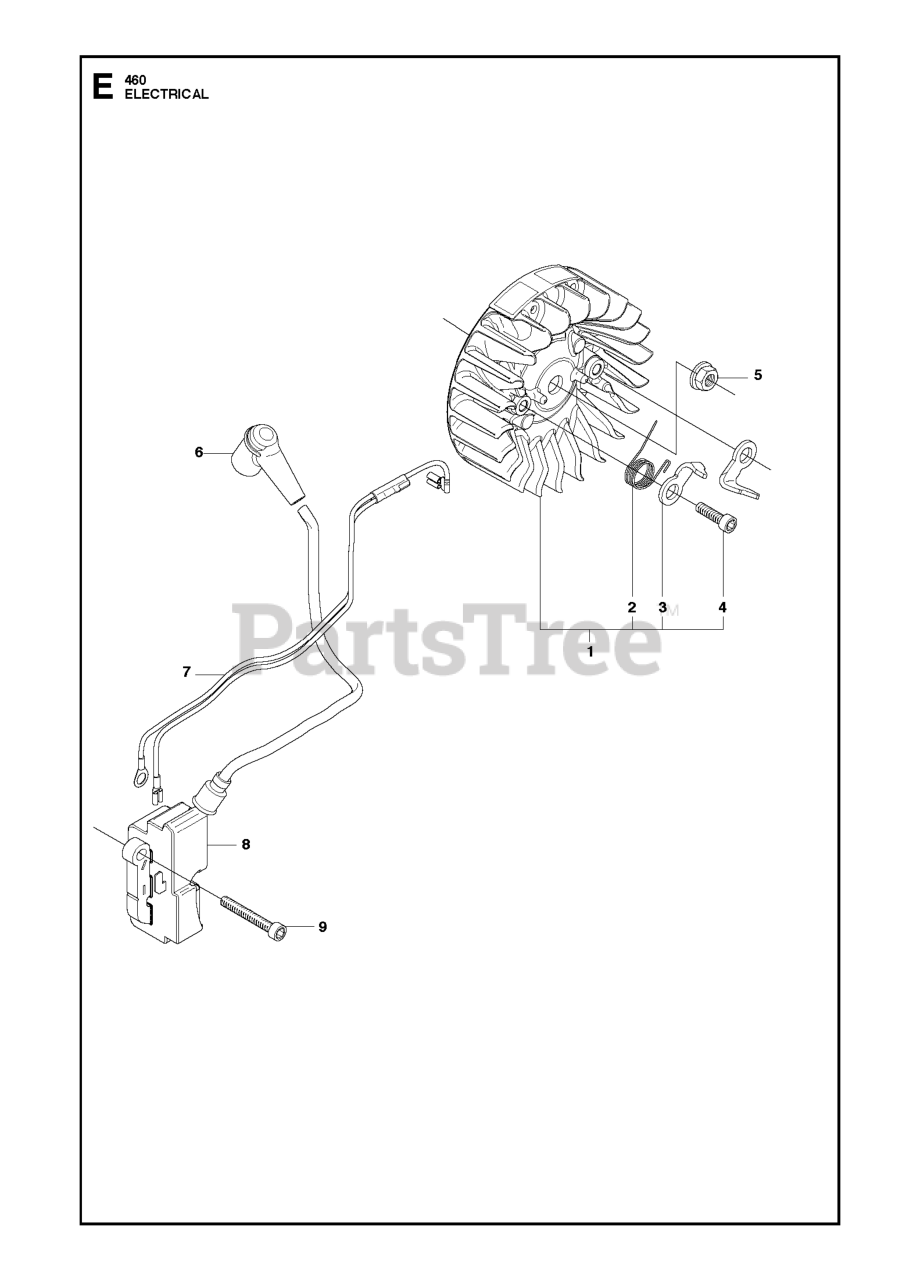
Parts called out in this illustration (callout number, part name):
5	NUT W/ WASHER
6	SPARK PLUG CONN. KIT
7	CABLE ASSY
8	IGNITION MODULE
